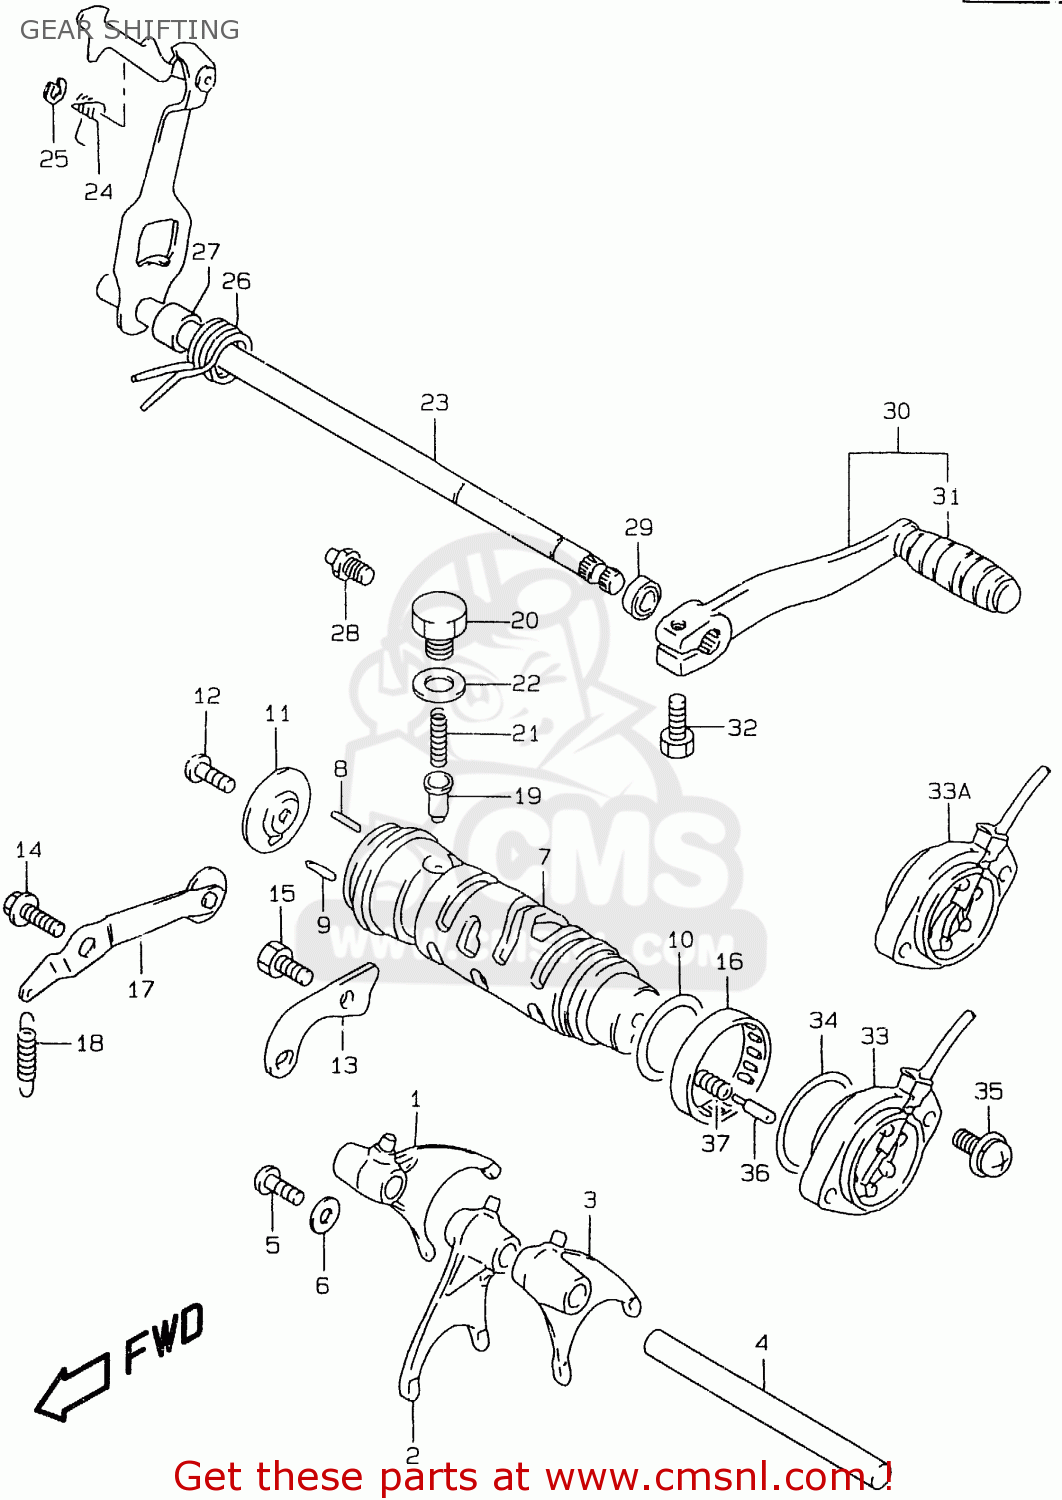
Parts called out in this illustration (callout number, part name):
1	FORK,GEAR SHIFT NO.1
2	FORK,GEAR SHIFT NO.2
3	FORK,GEAR SHIFT NO.2
4	SHAFT,GEAR SHIFT FORK
5	SCREW
6	WASHER
7	CAM,GEAR SHIFT
8	PIN(4X18.5)
9	PIN
10	SHIM(26X32.5X0.3)
11	RETAINER,GEAR SHIFT CAM DR PIN
12	SCREW 6X16
13	GUIDE,GEAR SHIFT CAM
14	BOLT(6X14.6)
15	BOLT
16	BEARING(40X47X12)
17	STOPPER,GEAR SHIFT CAM NO.1
18	SPRING
19	STOPPER,GEAR SHIFT CAM NO.2
20	HOLDER,GEAR SHIFT CAM STOP SPR
21	SPRING
22	GASKET(13.8X18.8X4.8) (NAS)
23	SHAFT,GEAR SHIFT
24	SPRING
25	E-RING
26	SPRING
27	SPACER(12X20X15.3)
28	STOPPER,GEAR SHIFT CAM
29	OIL SEAL
30	LEVER ASSY,GEAR SHIFT
31	RUBBER,GEAR SHIFT PEDAL
32	BOLT
33	BASE ASSY,NEUTRAL SW TERMINAL
33A	BASE ASSY,GEAR SHIFT TERMINAL
34	O-RING (D:2.4 ID:26.2)
35	SCREW
36	PIN(5X15.5)
37	SPRING
